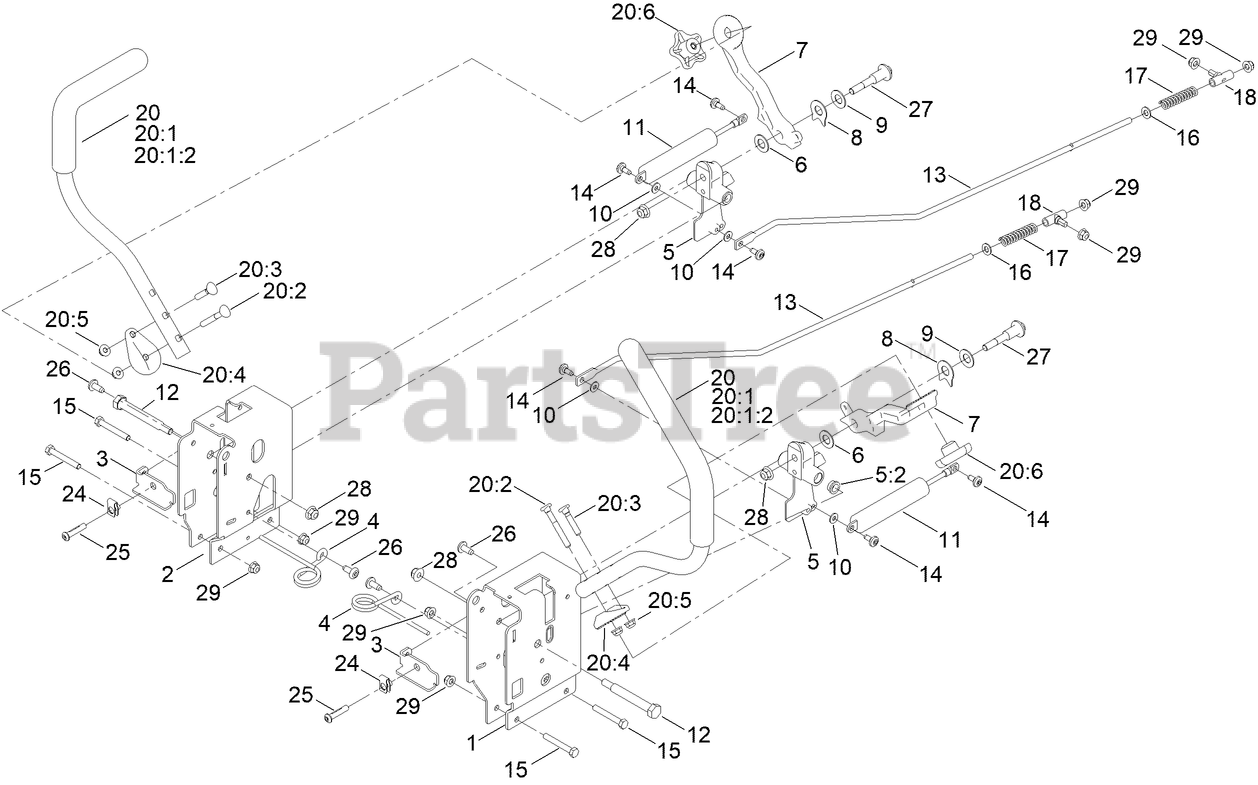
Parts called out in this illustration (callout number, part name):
1	CONTROL BOX - LH G7
2	CONTROL BOX - RH G7
3	ADJUSTMENT PLATE-CONTROL BOX
4	SPRING-TORSION
5	PIVOT ARM ASM
5:2	BUSHING-FLANGE
6	WASHER-NYLON
7	ARM-CONTROL, 32 TEETH
8	SPACER, ANTI-ROTATION
9	WASHER-BELLEVILLE
10	WASHER
11	DAMPER - NON CAVITATING
12	BOLT-PIVOT
13	ROD-HYDRO
14	SCREW-SHOULDER
15	SCREW-HH
16	WASHER-PLAIN
17	SPRING-COMPRESSION
18	MOUNT-ROD, HYDRO
20	HANDLE-CONTROL, ASM
20:1	HANDLE-CONTROL,
20:2	SCREW-HANDLE
20:3	SCREW-HANDLE
20:4	DISC-ADJUSTMENT HANDLE, 32 TEETH
20:5	NUT-HF
20:6	KNOB-HANDLE
25	SCREW-HSBH
27	BOLT-PIVOT
28	NUT-HF, NI
29	NUT-HF, NI
